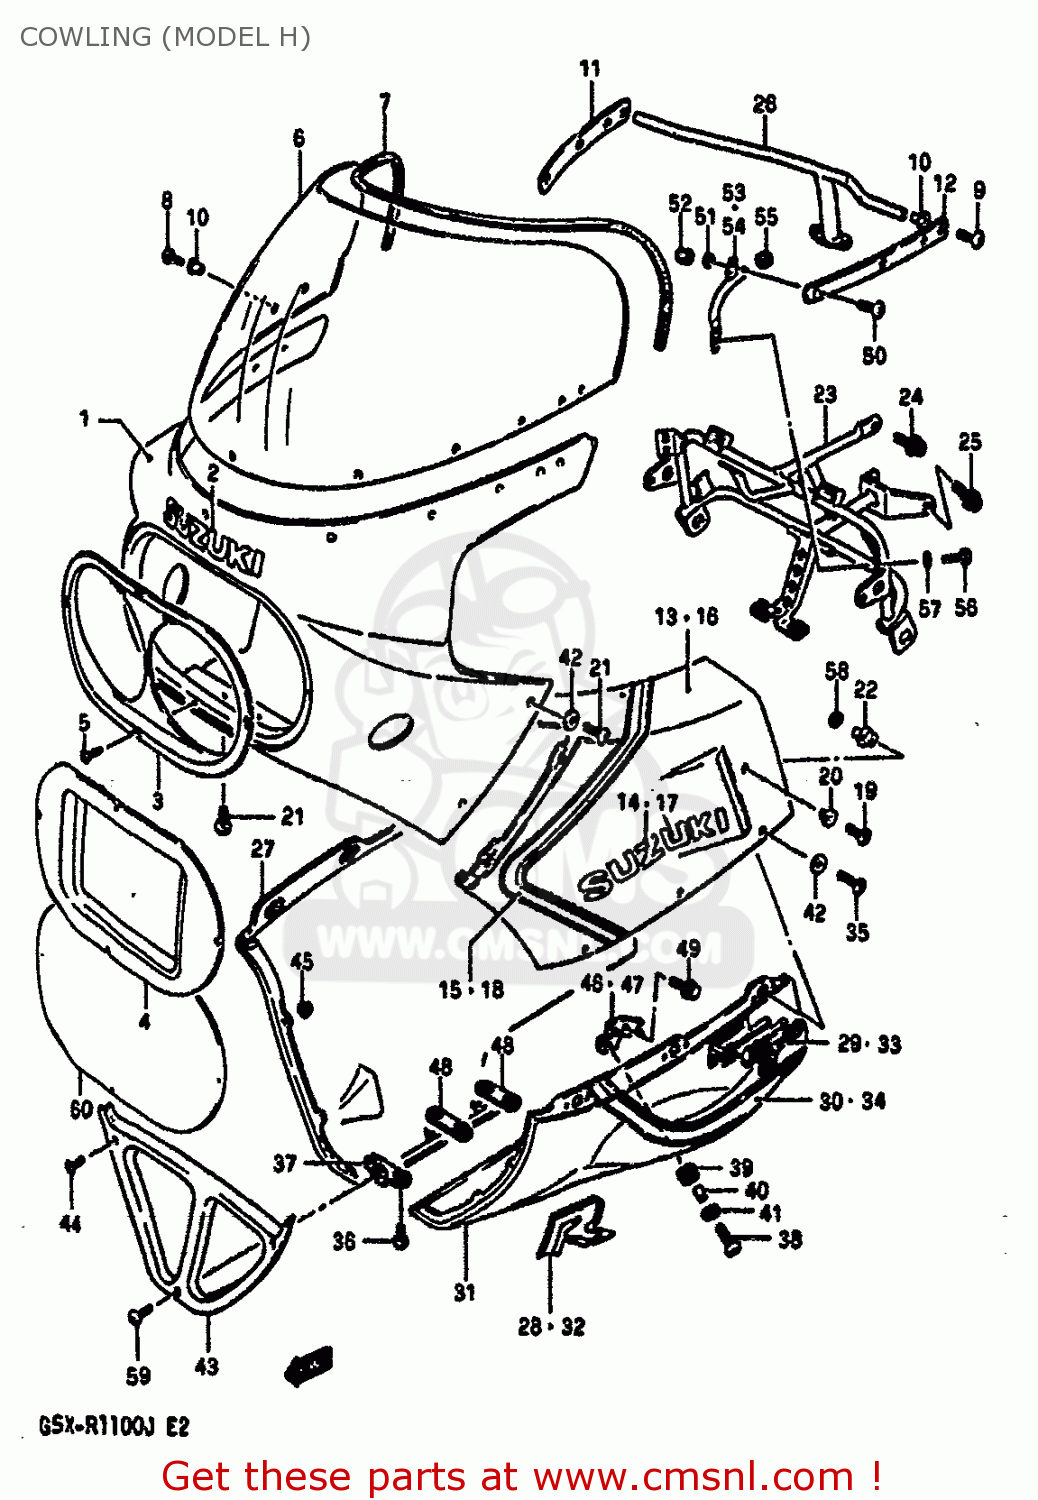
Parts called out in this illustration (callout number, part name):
1	BODY ASSEMBLY,COWLING
2	EMBLEM
3	COVER,COWLING,FRONT
4	COVER,FRONT (BLUE)
5	SCREW
6	WINDSCREEN
7	MOLDING
8	SCREW(5X14)
9	SCREW(5X18)
10	NUT,COWLING SCREEN
11	PLATE,RR VIEW MIRROR,R
12	PLATE,RR VIEW MIRROR,L
13	COVER COMP,COWLING SIDE,RIGHT
14	EMBLEM
15	TAPE SET,COVER SIDE,RIGHT
16	COVER,COWLING SIDE,LEFT
17	EMBLEM
18	TAPE SET,COVER SIDE,LEFT
19	SCREW(6X12)
20	WASHER
21	SCREW(6X16)
22	CUSHION,COWLING
23	BRACE,COWLING FR
24	BOLT
25	BOLT
26	BRACE,COWLING BODY RR
27	COVER COMP,COWLING,LOWER
28	EMBLEM,COWLING LWR
29	EMBLEM
30	TAPE SET,COWL LWR,R
31	COVER COMP,COWLING,LOWER
32	EMBLEM,COWLING LWR
33	EMBLEM
34	TAPE SET,COWLING,LOWER
35	SCREW(6X16)
36	SCREW(6X16)
37	BRACE,COWLING LWR COVER
38	SCREW(6X20)
39	CUSHION
40	SPACER
41	WASHER(6.5X18X1)
42	WASHER
43	COVER,COWLING,LOWER,FRONT
44	SCREW(5X14)
45	NUT
46	BRACE,COWLING LWR,R
47	BRACE,COWLING LWR,L
48	BRACE,COWLING LWR COVER RR
49	BOLT
50	SCREW(6X16)
51	WASHER,LOCK
52	NUT 6MM
53	BRACE,MIRROR,R
54	BRACE,MIRROR,L
55	PLUG(OD:12)
56	BOLT 6X16
57	WASHER,LOCK
58	WASHER
59	SCREW(6X16)
60	COVER,HEADLAMP
